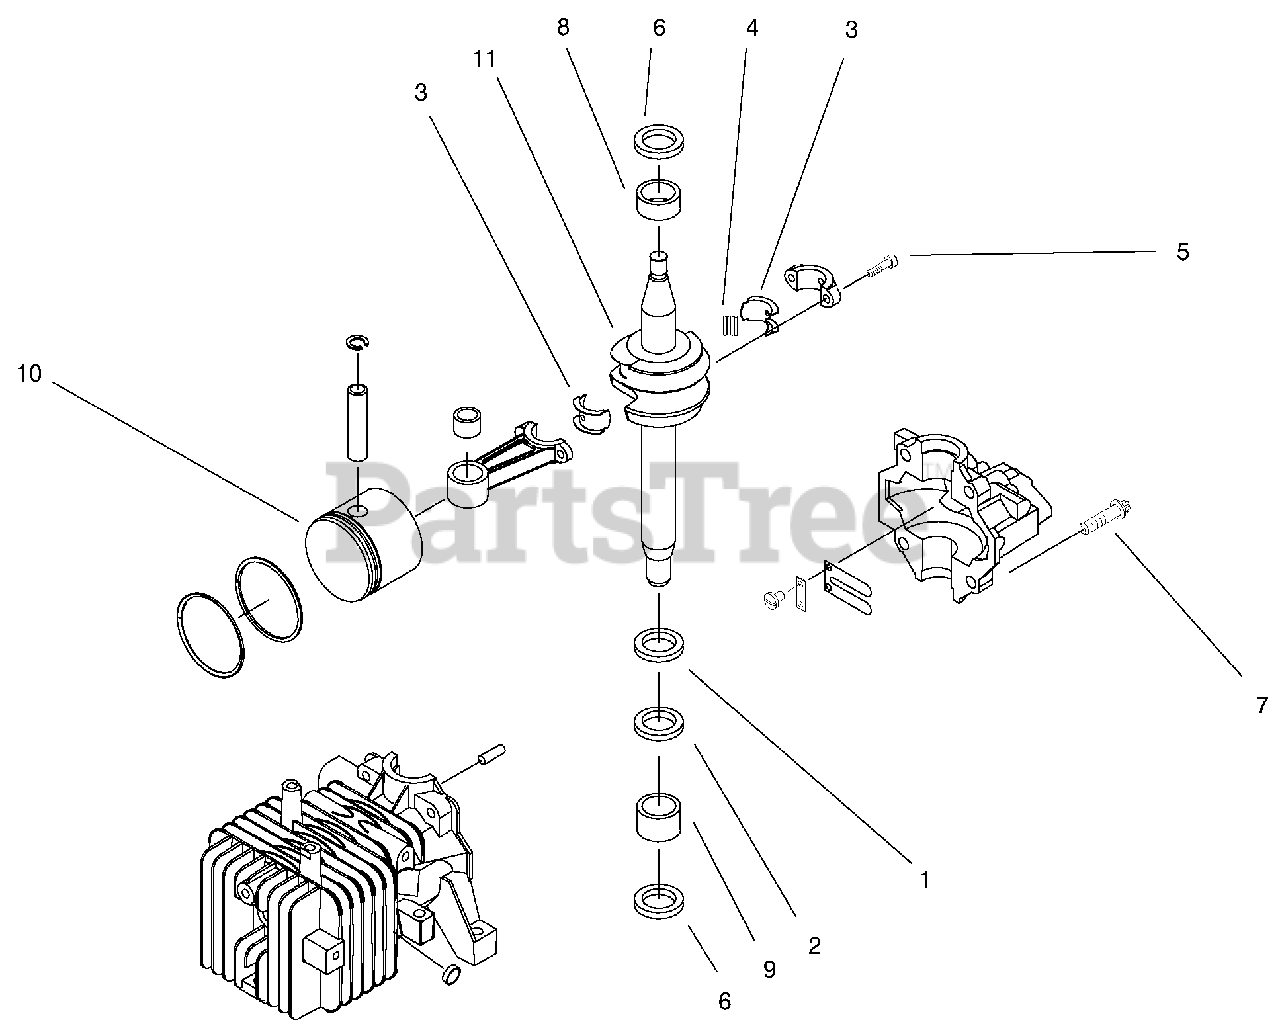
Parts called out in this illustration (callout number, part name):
1	Bearing-Thrust
2	Bearing-Thrust
3	Liner-Split
4	Roller-Strip
5	Screw-HSH
6	Seal-Oil
7	Screw,H.w.hd.
8	Bearing
9	Bearing
10	Piston&conn Rod
11	Crankshaft
